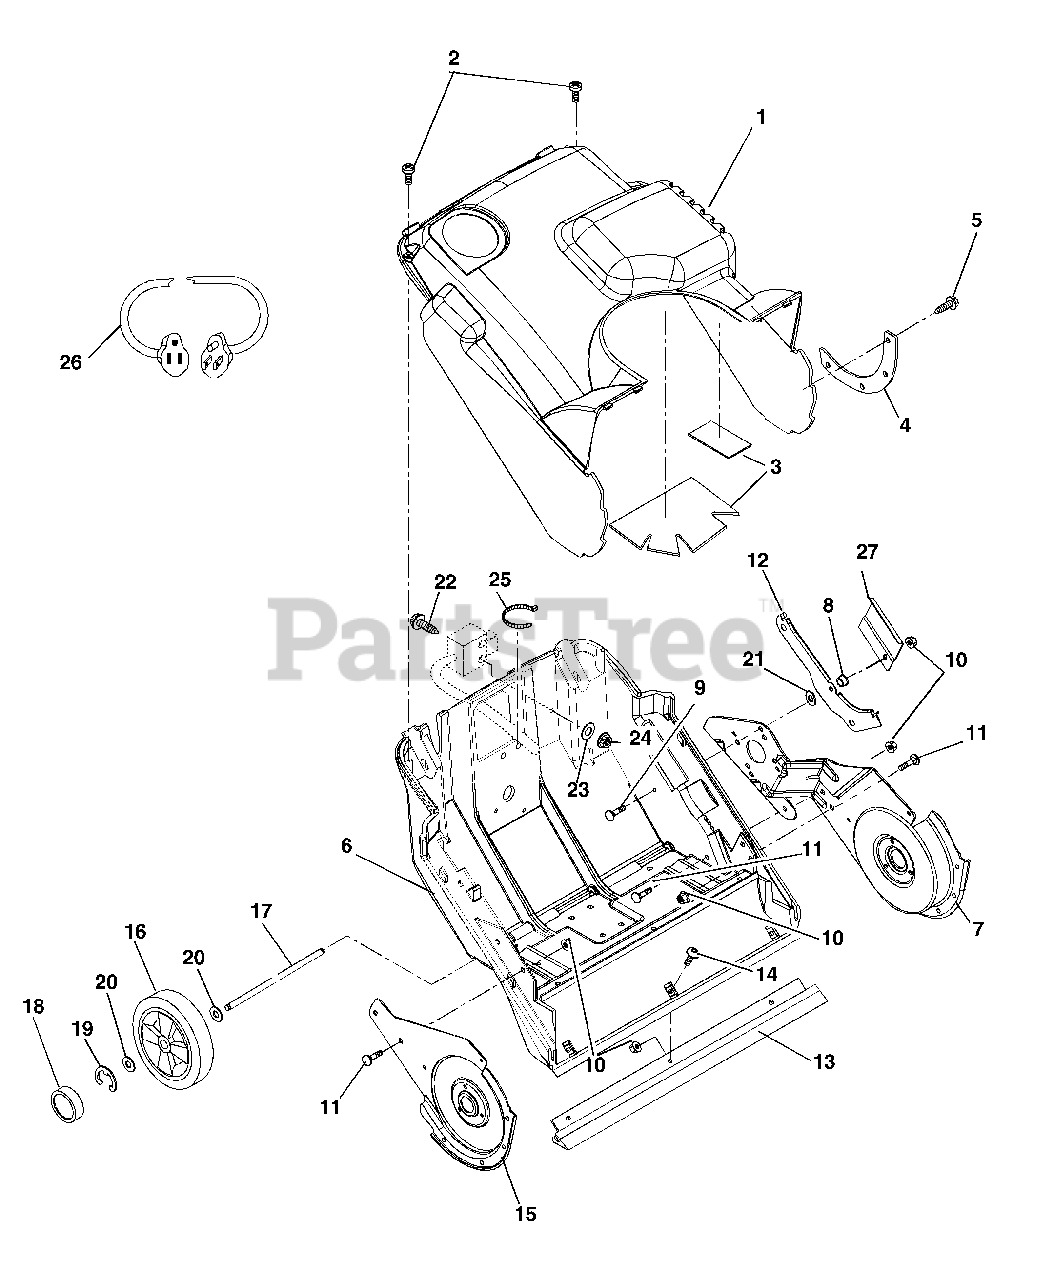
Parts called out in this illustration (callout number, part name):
1	COWL ASSY-REPLACEMENT
2	SCR-SPEC-TAP #10X1.0
3	SHEET-HEAT REFLECTIVE
4	PLATE-COWL RETAINER
5	SCR-TAP 12-24X.50 HWH TR BLACK
6	CHASSIS
7	SUPPORT-BRG,LH
8	BSHG-FLG .265X.437X.250X.750
9	@BLT-RDHDSQNK .25-20X1.25 G5YZ
10	NUT-LK-FLG .250-20 PL BLK
11	@BLT-RDHDSQNK .25-20X.75 G5YZ
12	GUIDE-CABLE
13	BLADE-SCRAPER
14	SCR-MCH .25-20X.75 TXTR YWZC
15	SUPPORT-BRG,RH
16	T/WHL ASSY 7.0X1.5
18	CAP-HUB
19	RG-RTNG-EXT .375X.035 TYP E
20	@WSHR-FL-STL.406X.812X.065 YWZ
21	@WSHR-FL-STL.312X.734X.065 YWZ
22	@SCR-MCH 8-32X2.75 HWH YWZC
23	@WSHR-FL-STL.219X.50X.049 YWZC
24	@NUT-LK-NYL 8-32 W/INSTR YWZC
25	CABLE TIE LG 5-1/2
26	CORD, ELECTRIC START CORD 120V
27	DEFLECTOR, EXHAUST
